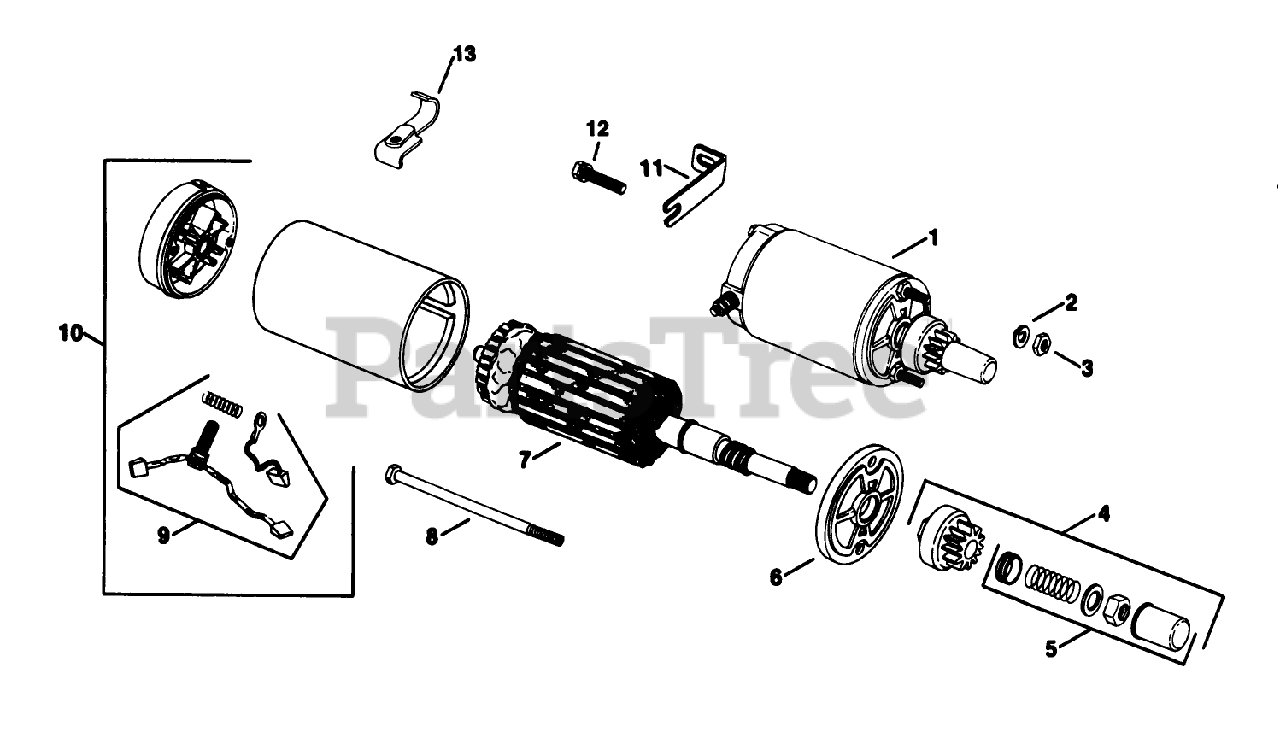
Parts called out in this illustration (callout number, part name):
1	Starter Assembly
2	Washer
4	Kit-Drive
5	Kit-Drive Parts
6	Cap-Drive End
7	Armature
9	Kit-Brush
10	Kit-Commutator End Cap
11	Bracket-Starter Support
12	Screw-H.C
13	Bracket-Mounting
